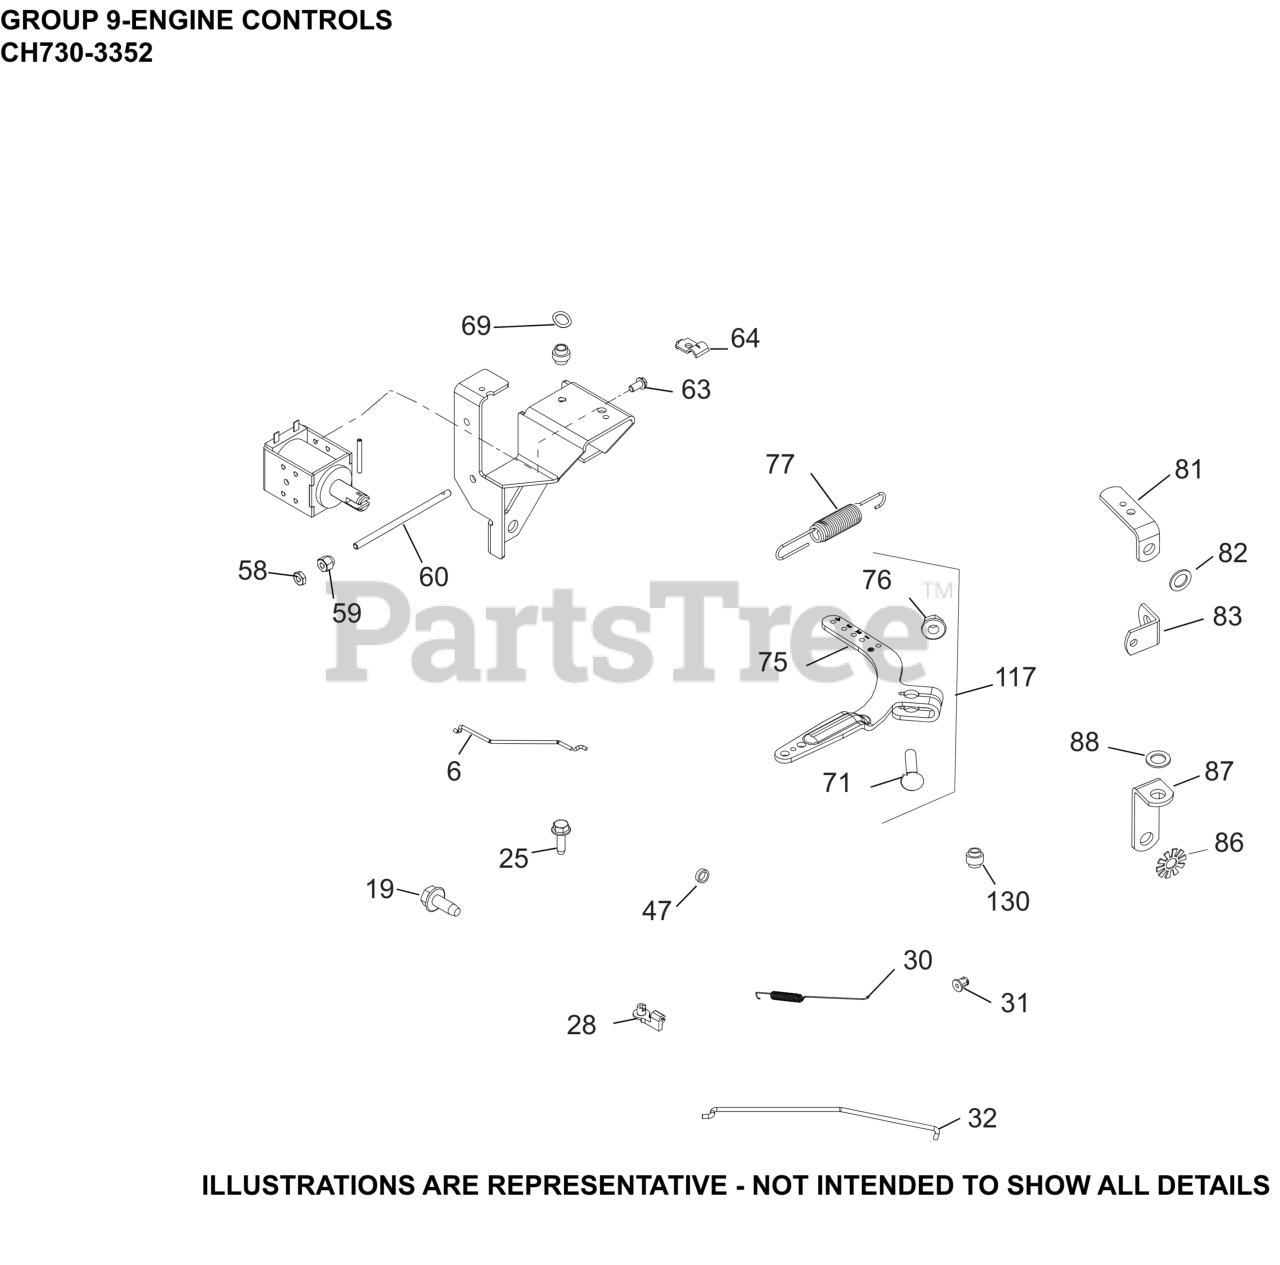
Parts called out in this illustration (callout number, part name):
6	LINKAGE, CHOKE
19	SCREW, THREAD FORMING
25	SCREW, THREAD FORMING
28	BUSHING, THROTTLE LINKAGE
30	SPRING, LINKAGE
31	BUSHING, LINKAGE RETAINING
32	LINKAGE, THROTTLE
58	NUT, MACH SCREW #10-32 GRD 2
59	NUT, ADJUSTING
60	ROD, SPEED CONTROL
63	SCREW,WSH HD TAP #10-24X13/32"
69	WASHER, SPRING 11/32"
71	BOLT, RD HD SQ NECK M6X1.0X25
75	LEVER, GOVERNOR - (#2409069S)
76	NUT, FLG M6X1.0
77	SPRING, GOVERNOR (GREEN)
82	WASHER,INT EXT TOOTH LOCK 1/4"
86	Washer, Int Ext Tooth
87	STRAP, LIFTING
117	LEVER, GOVERNOR ASSEMBLY
NI	LEVER, THROTTLE & CHOKE CONTROL
